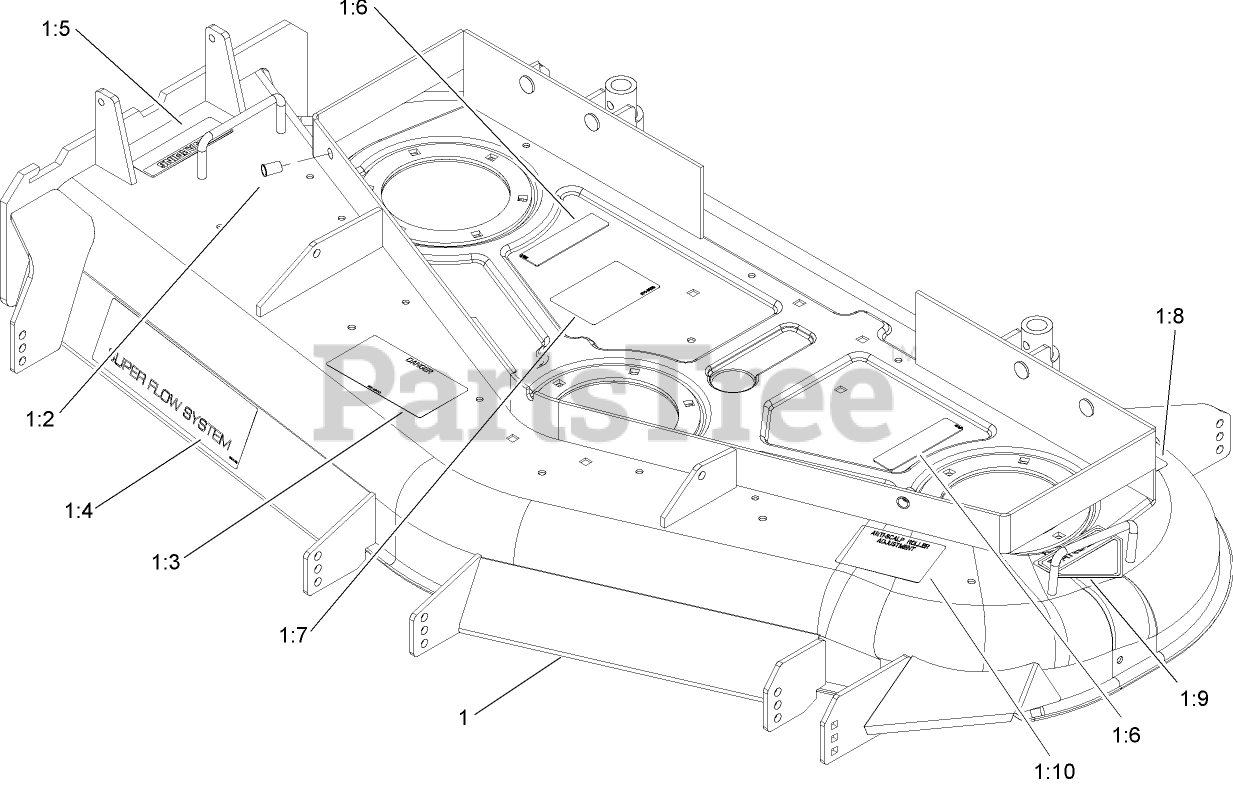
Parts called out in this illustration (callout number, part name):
1	52IN DECK ASM
1:2	INSERT-NUT
1:3	DECAL-DANGER, THROWN OBJECT
1:5	DECAL-WARNING
1:6	DECAL-DANGER
1:7	DECAL-ROUTING, BELT
1:8	DECAL-TORQUE
1:9	DECAL-DANGER
1:10	DECAL-ANTI SCALP
